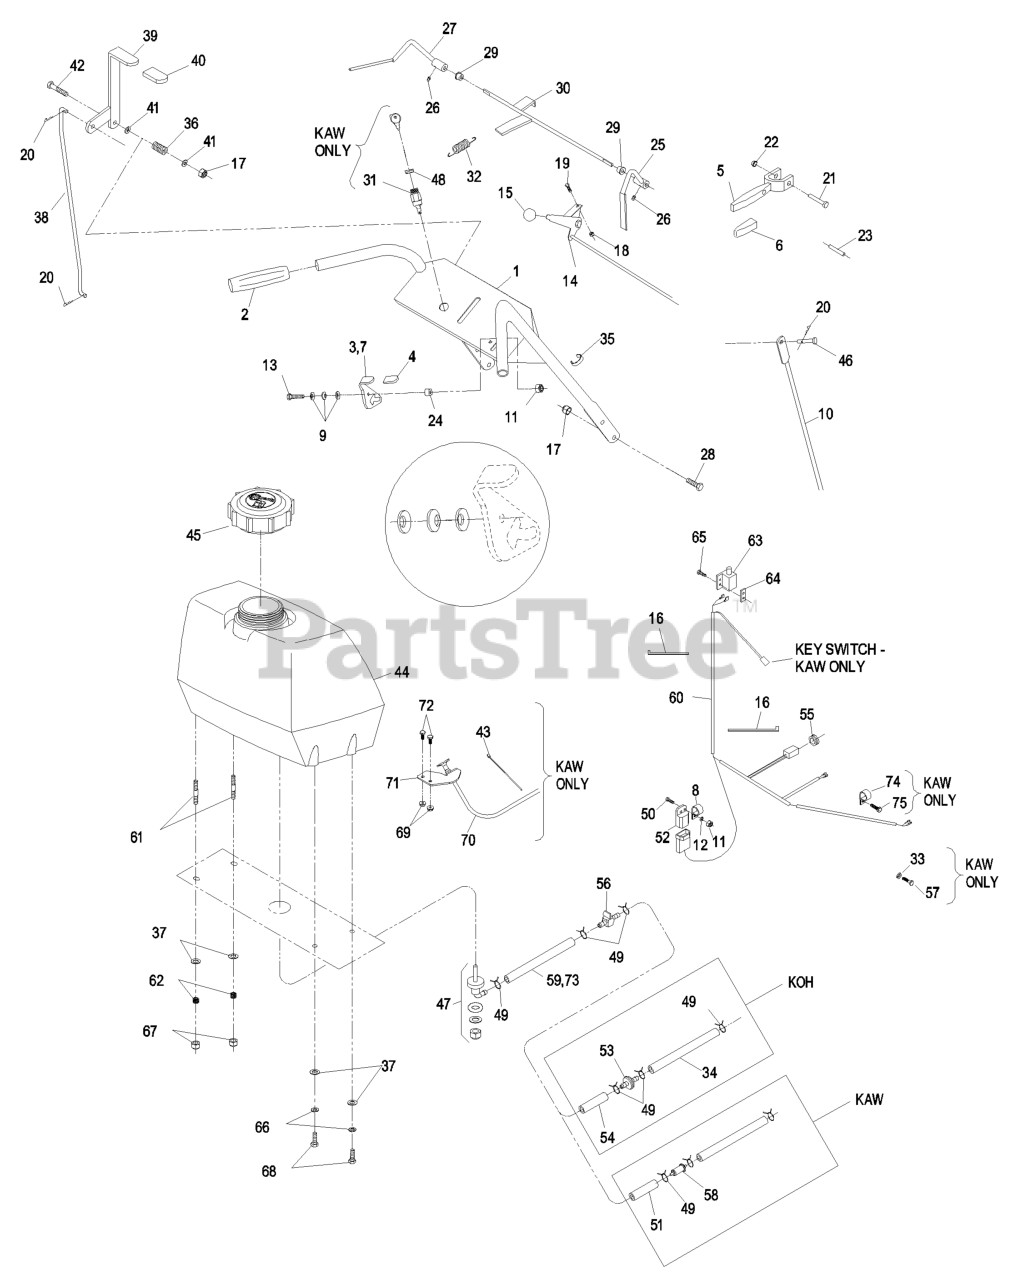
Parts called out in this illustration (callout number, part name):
1	KIT,HANDLE/DECALS METRO
4	GRIP-LATCH
5	DRIVE LEVER ASM
6	GRIP-LEVER, DRIVE
8	CLIP-LOOM
9	WASHER-SPRING
10	LINKAGE-WHEEL, DRIVE
11	NUT-LOCK, NI
12	WASHER-FLAT
13	SCREW-HH
14	CABLE-CONTROL, THROTTLE
15	KNOB-BALL
16	TIE-CABLE
17	NUT-LOCK, NI
18	NUT-LOCK, NI
19	BOLT-CARR
20	PIN-COTTER
21	PIN-LEVER, DRIVE
22	NUT-PUSH
23	PIN-ROLL
25	LEVER-RH
26	SCREW-SET
27	LEVER-LH
28	SCREW-HH
29	BUSHING-NYLON
30	WLD,ROD OPC
31	SWITCH & KEY (INCLUDES NU
32	SPRING-EXTENSION
33	WASHER-LOCK
34	HOSE-LINE, FUEL
35	CLIP-CABLE
36	SPRING-COMPRESSION
37	WASHER-PLAIN
38	LINKAGE-BLADE, UPPER
40	GRIP-LEVER
41	WASHER-FLAT
42	SCREW-HH
43	TIE-PLASTIC
44	ASM,FUEL TANK W/B
46	PIN-CLEVIS
47	FITTING-FUEL, BULKHEAD
48	NUT-SWITCH, IGNITION
50	SCREW-HH
51	HOSE-FUEL
52	MODULE-INTERLOCK
54	HOSE-LINE, FUEL
55	GROMMET
56	VALVE-FUEL
57	SCREW-HH
58	Kawasaki Pn 41019-1055 W/6" Fuel Line (Kaw)
59	HOSE-FUEL
60	HARNESS-WIRE
61	STUD
62	SPRING-TANK, FUEL
63	SWITCH-OPEN, NORMALLY
64	PLATE-TAPPED
65	SCREW-PPH
66	WASHER-LOCK
67	NUT-LOCK, NI
68	SCREW-HH
70	CABLE-CHOKE
71	BRACKET-CABLE, CHOKE
72	SCREW-HH
73	HOSE-FUEL
74	CLIP-LOOM
75	SCREW-HH
